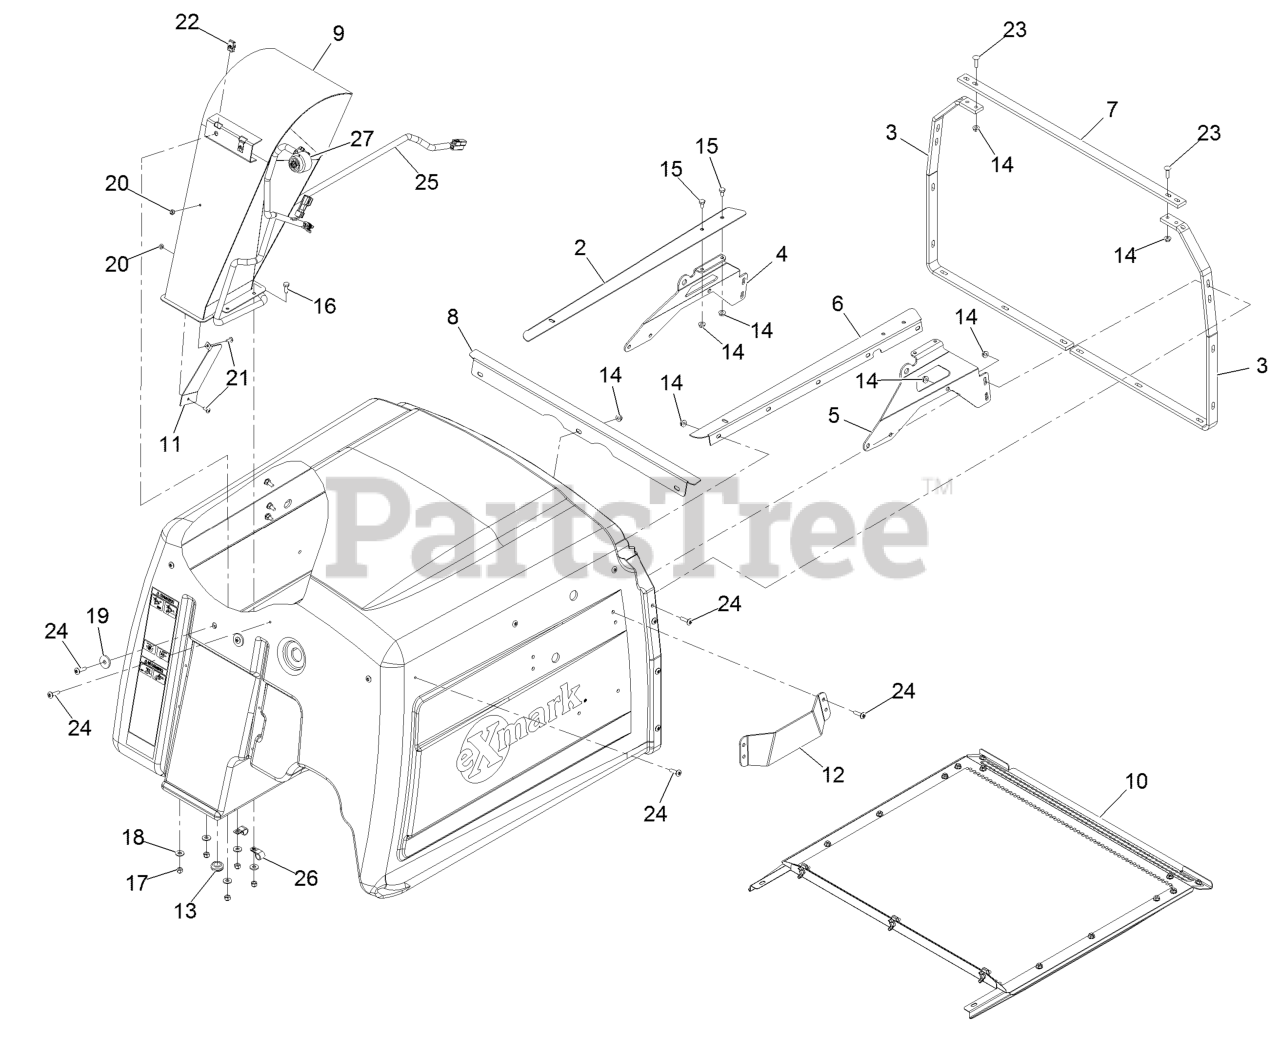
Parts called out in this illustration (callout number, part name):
2	ANGLE-SCREEN TRACK, RH
3	REINFORCEMENT-HOPPER
4	BRACE-DOOR PIVOT, RH
5	BRACE-DOOR PIVOT, LH
6	ANGLE-SCREEN TRACK, LH
7	BRACKET-FRAME CONNECT
8	CHANNEL-SCREEN, FRONT
10	HOPPER SCREEN ASM
11	DEFLECTOR-DISCHARGE CHUTE
12	PLATE-GUARD
13	GROMMET
15	SCREW-HH
16	SCREW-HH
17	NUT-LOCK, NI
18	WASHER-FLAT
20	NUT-LOCK, NI
21	SCREW-PTH
22	Nut-Retainer-Panel 1/4-20
23	SCREW-CARR
24	SCREW-TTH
25	HARNESS-WIRE, HOPPER
26	CLIP-LOOM
27	ALARM-TONE, DUAL
